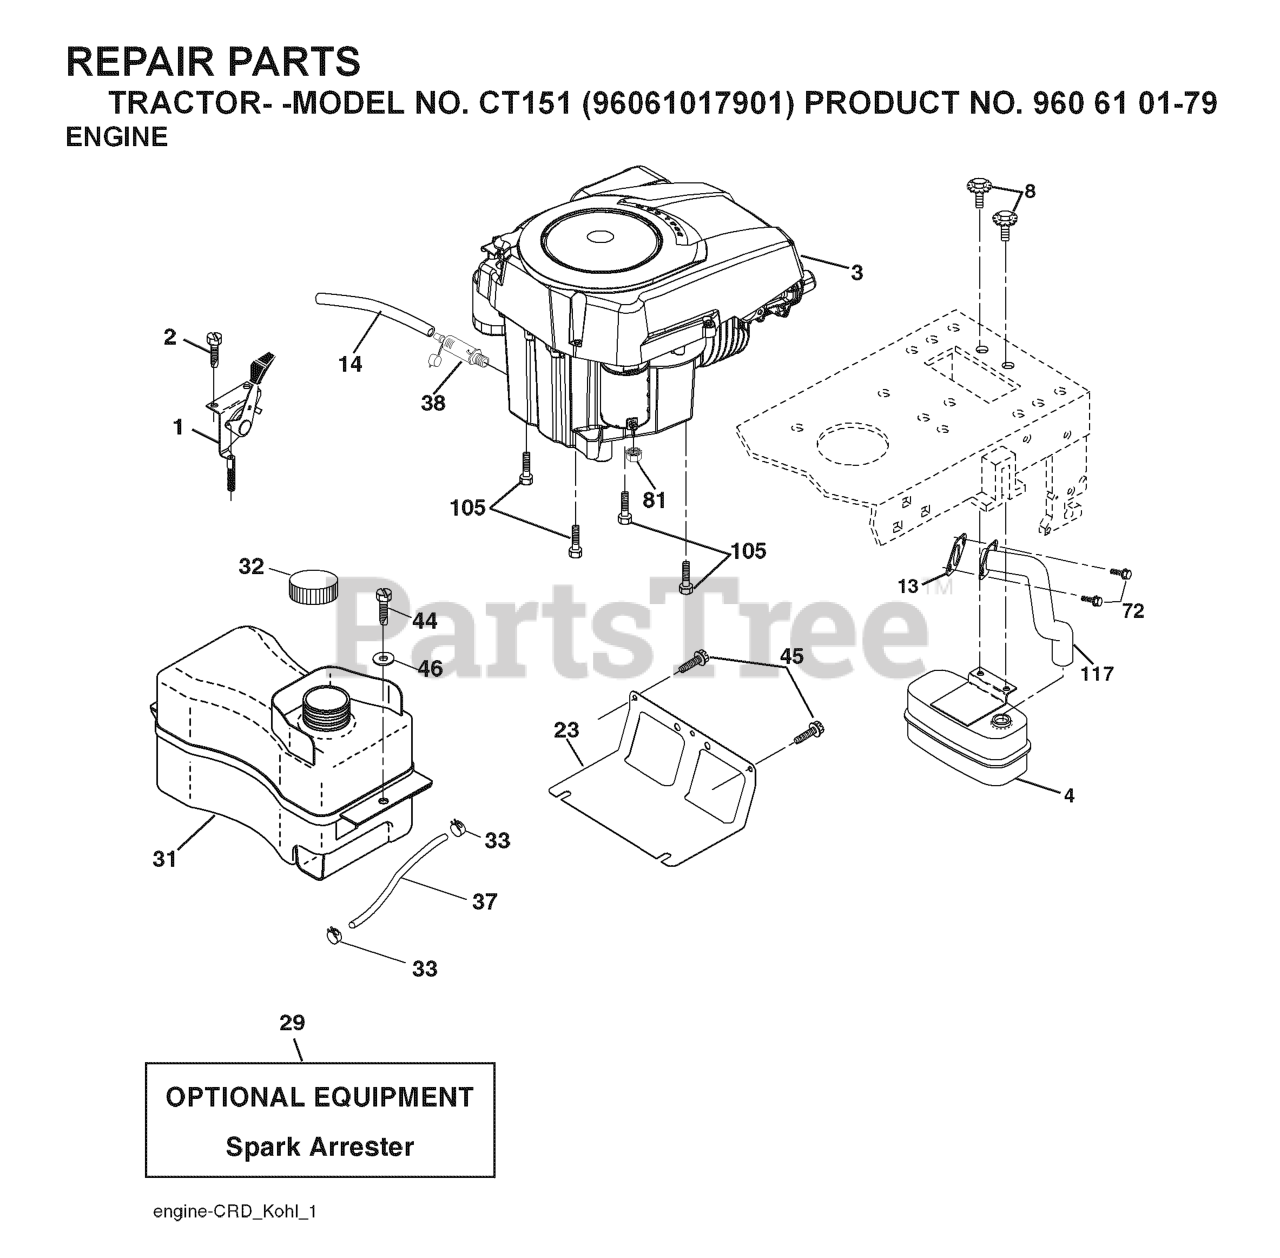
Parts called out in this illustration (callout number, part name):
1	CONTROL.TH/CK.C.
2	SCREW
4	MUFFLER.SINGLE.CYL.KOHL/B&S
8	BOLT.5/16-18UNCX3/4 W/SEMS.BLK
13	GASKET.EXHAUST.KOHLER
14	TUBE, DRAIN OIL ASM.
23	SHIELD.BROWNING.DBR.GUARD
29	KIT.SPARK ARRESTOR 794945 B&S
31	RP TANK FUEL FRT 1.5 GAL
32	FUEL CAP
33	HOSE CLAMP
37	LINE.FUEL.20
38	PLUG DRAIN OIL EASY
44	SCREW HEXWSHR 1/4-20X3/4
45	SCREW, 3/8-16X3/4
72	SCREW.SOCKET HD.5/16-1
81	NUT
91	BUSHING.1.375OD
105	SCREW 3/8-16X1
117	RP.TUBE.EXHAUST.KOHL.COURAGE
119	LENKRAD
120	GUARD 532199767
122	SCREW.1/4-20X5/8
123	SCREW, 5/16-18 X 1/2
126	SCREW
